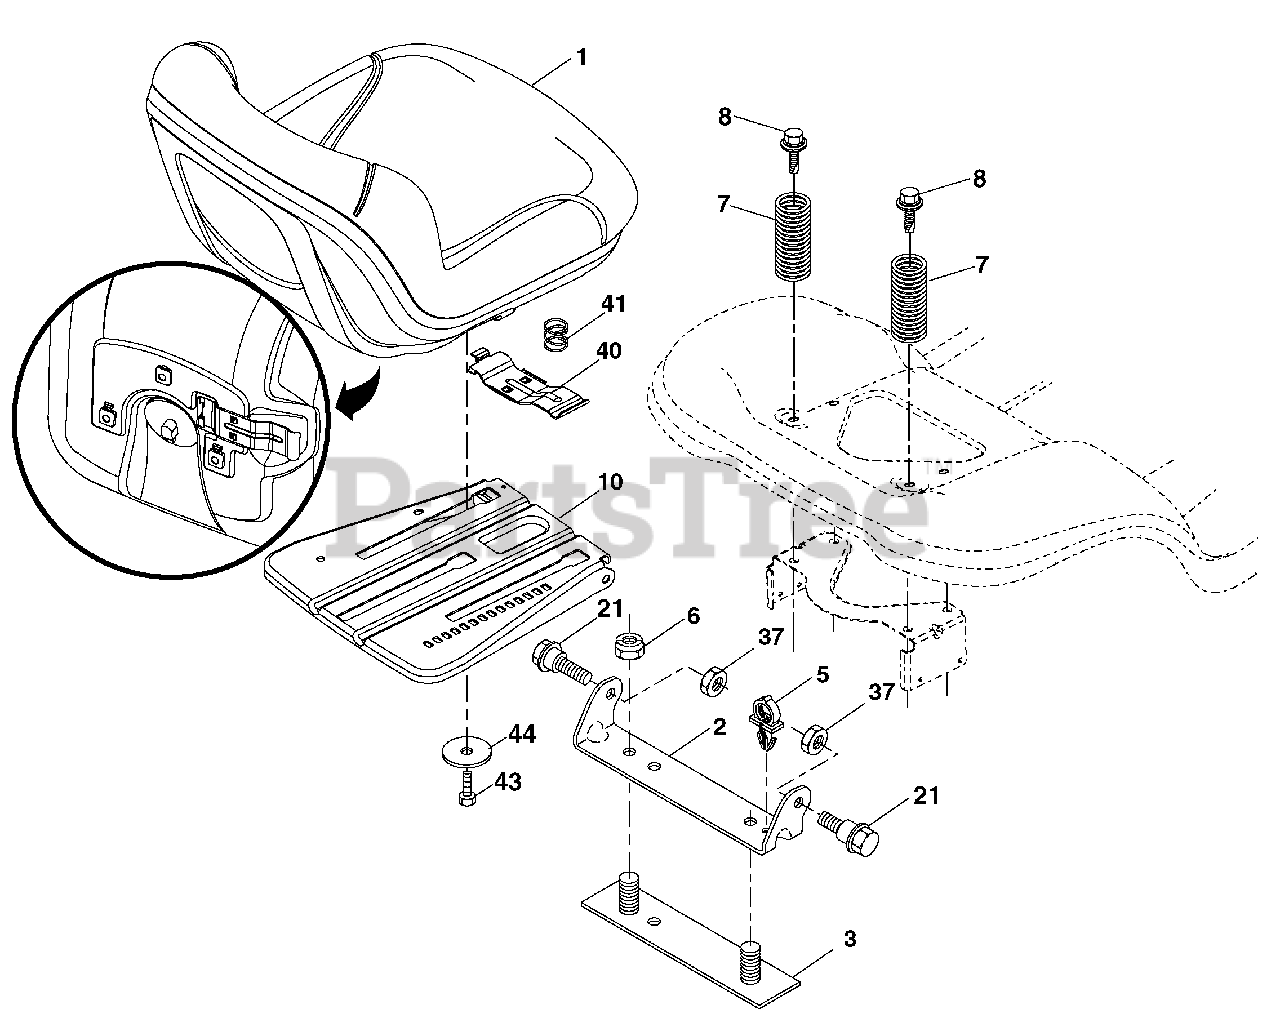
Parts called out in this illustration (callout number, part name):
1	Seat
2	Bracket Pivot Fender
3	Strap, Asm Fender
5	Clip, Push In, Hinged
6	Nut, Lock W/Ins. 3/8-16 unc
7	Spring, Seat Cprsn
8	Bolt 5/16-18 uncx 3/4 w/Sems
10	Pan, Seat
14	Bolt Rdhd Sht Nk 1/4-20 x 1-1/2
21	Bolt, Shoulder 5/16-18
37	Nut, Lock 5/16-18 unc
40	Handle Slide Seat
41	Spring Latch Seat
43	Bolt Fin Hex 3/8-16 UNC x 3/4
44	Washer 13/32 x 2-3/8 x 12Ga.
